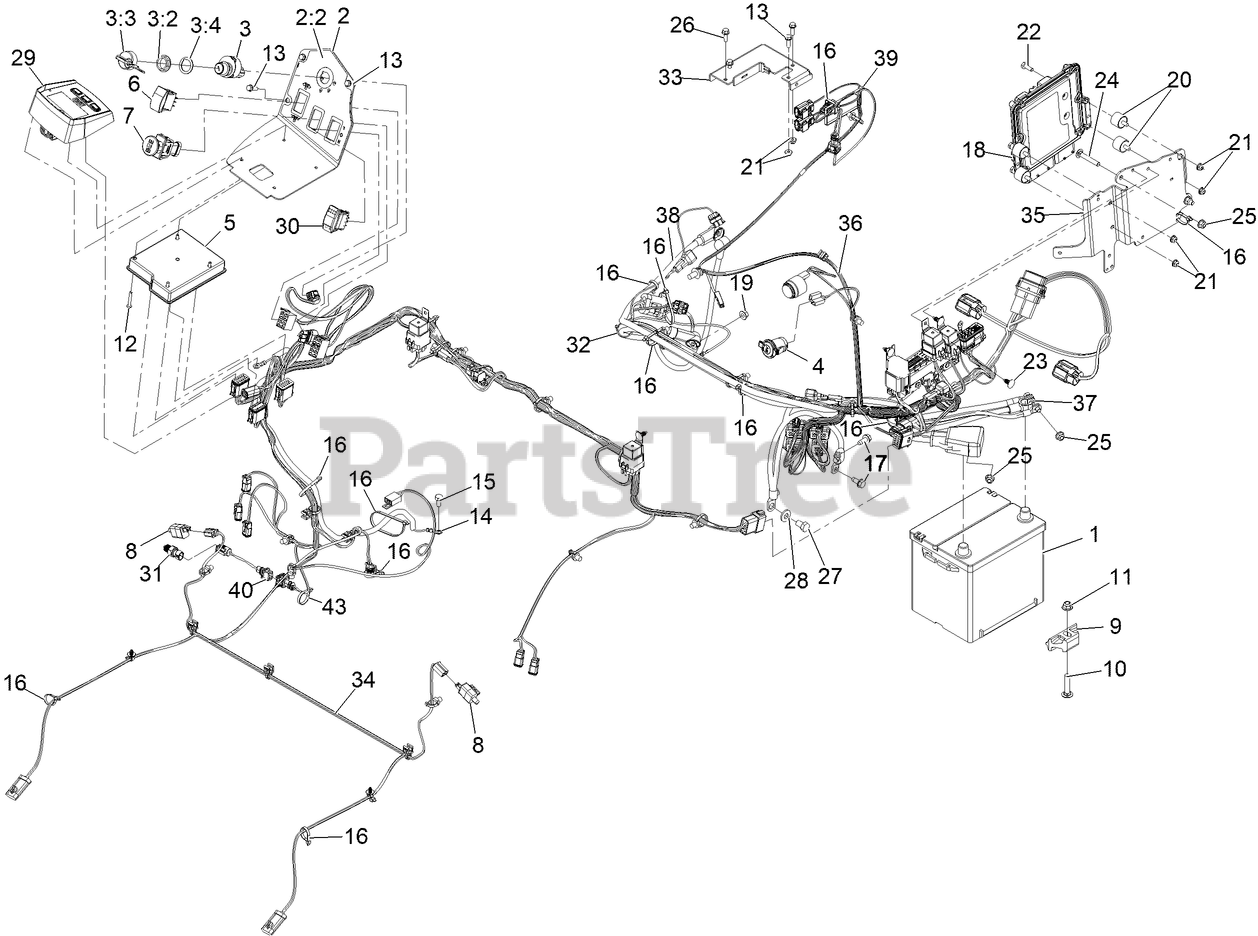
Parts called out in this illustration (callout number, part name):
1	Battery-Dry
2	ASM, CONSOLE W/ DECAL 144
2:2	DECAL-CONTROL PANEL
3	IGNITION SWITCH ASM
3:2	NUT-MOUNTING
3:3	IGNITION KEY SET
3:4	WASHER-BACKUP
4	PORT-POWER, 12V
5	Module-Mcu
7	SWITCH-PTO, SEALED
9	RETAINER-BATTERY
10	SCREW-CARR
11	NUT-HF, NI
12	SCREW-PPH
13	SCREW-HWH
14	HARNESS-WIRE, JUMPER
15	BOLT
16	TIE-CABLE
17	Screw-HWH 5/16-18 X 3/4 Tf
18	Electronic Control Unit
20	MOUNT-CYLINDRICAL
22	SCREW-HH
23	PLUG-PLASTIC
24	BOLT-CARR
25	NUT-HF, NI
26	SCREW-HHF
27	SCREW-HH
28	WASHER-BELLEVILLE
29	MODULE, LDU
30	SWITCH-ROCKER, ON-NONE-ON
31	Sensor-Temperature
32	CLIP-TIE
33	BRACKET-SENSOR, DPF
34	HARNESS-WIRE, MAIN
35	PLATE-ECU MOUNT
36	HARNESS-WIRE, ENGINE
37	CABLE-BATTERY, RD AND BK ASM
38	CABLE-BATTERY, BK ASM
39	TIE-CABLE
40	Harness-Jumper Temp Sense
43	TIE-CABLE
